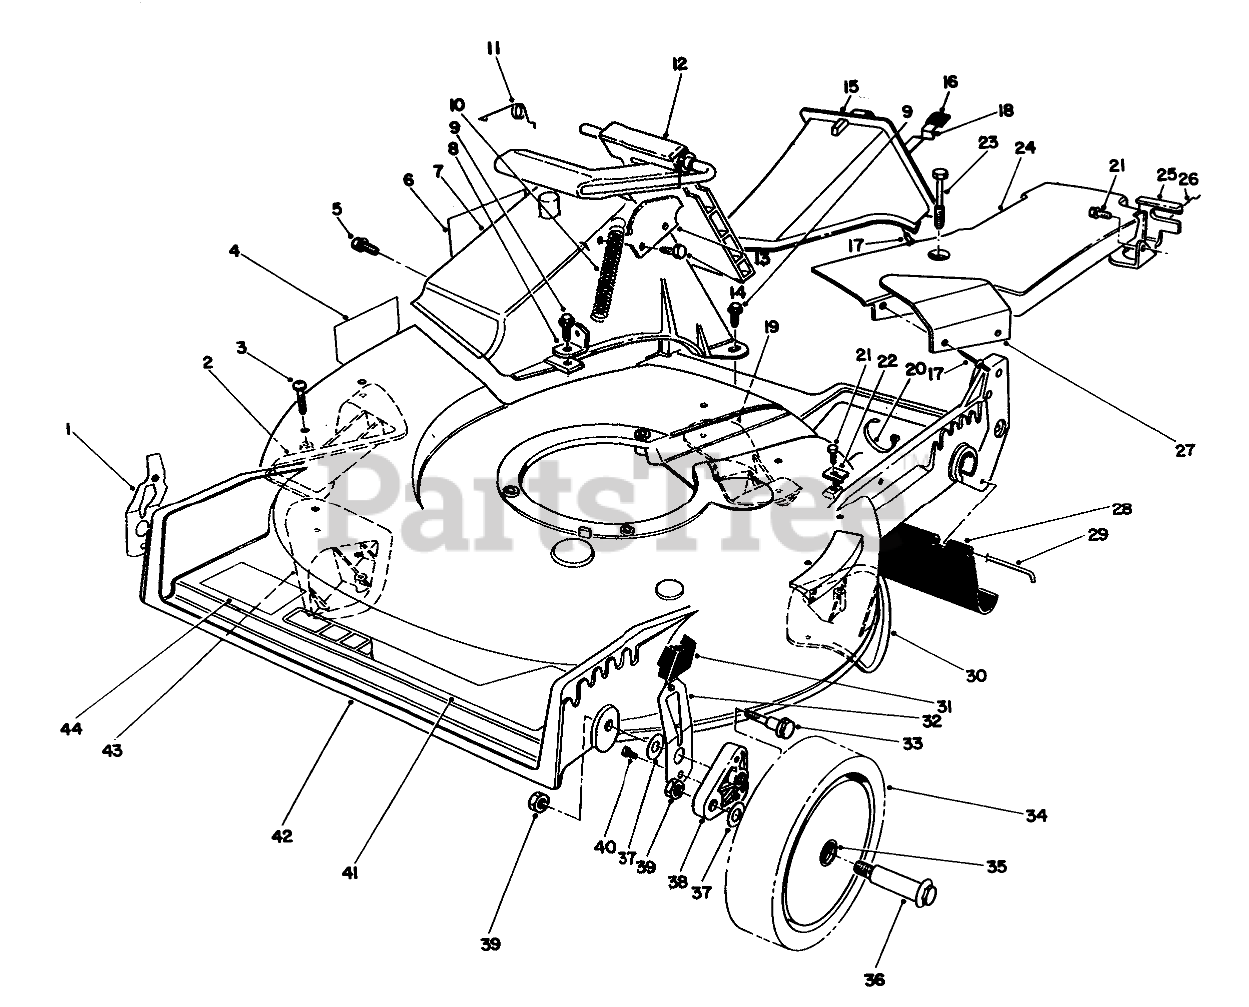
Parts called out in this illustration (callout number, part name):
1	RH SPRING ARM ASSEMBLY
2	KICKER
3	SCREW-PPH
4	DECAL-DANGER
5	SCREW AND WASHER ASM
6	DECAL - DANGER
7	TUNNEL-DISCHARGE
8	Bracket-Spring
9	SCREW-HWH
10	SPRING-DOOR
11	RETAINER-DOOR
12	Discharge Door Assembly
13	DOOR LATCH PLATE
14	Screw-Hex Washer Hd.Self Tapping
15	Plug Assembly(Incl. Ref . #16-18)
16	GRIP-LATCH
17	RIVET-HEAD, FLAT
18	LATCH-PLUG, DISCHARGE
19	KICKER
20	TIE-CABLE
21	Screw-Muffler
22	CLAMP-CABLE
23	SCREW-HHFTF
24	Belt Cover Assembly(Incl. Ref. #17 & 27)
25	Bracket-Adj. Trac
26	RETAINER-CABLE
27	HEAT SHIELD
28	SHIELD-TRAILING
29	ROD-SHIELD
30	KICKER
31	KNOB-ARM
32	LH SPRING ARM ASSEMBLY
33	SCREW-SHOULDER
34	Wheel & Tire Assembly(Incl. Ref. #35)
35	BUSHING
36	WHEEL BOLT
37	WASHER
38	ARM-PIVOT, FRONT
39	Nut
40	SCREW-HWH
41	DECAL - DECK
42	Housing Assembly(Incl. Ref. #2-4, 19, 29& 43)
43	KICKER
44	DECAL
